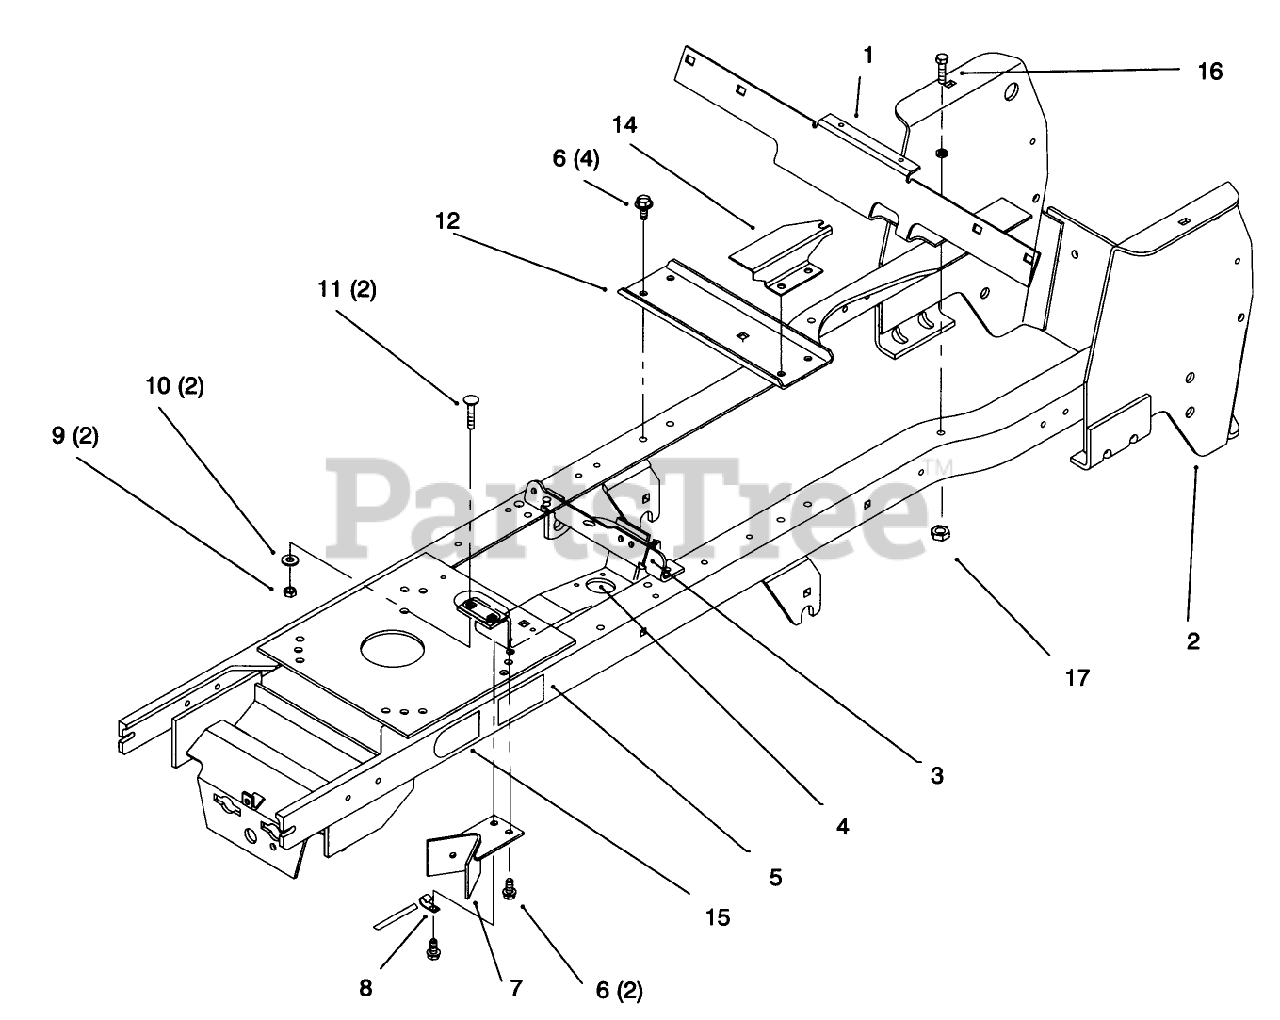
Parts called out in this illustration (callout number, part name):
3	TIE-CABLE
5	DECAL-BELT INSTRUCTIONS
6	SCREW-HWHTF
7	PTO STOP ASM
8	CLIP
9	NUT-LOCK, NI
10	WASHER-PLAIN
11	BOLT-CARR
12	BRACKET-IDLER PLATE
14	BRACKET-HOC GAGE
15	SCREW-HH
15	DECAL-ATTACH A-MATIC
16	SCREW-HH
17	NUT-LOCK, NI
